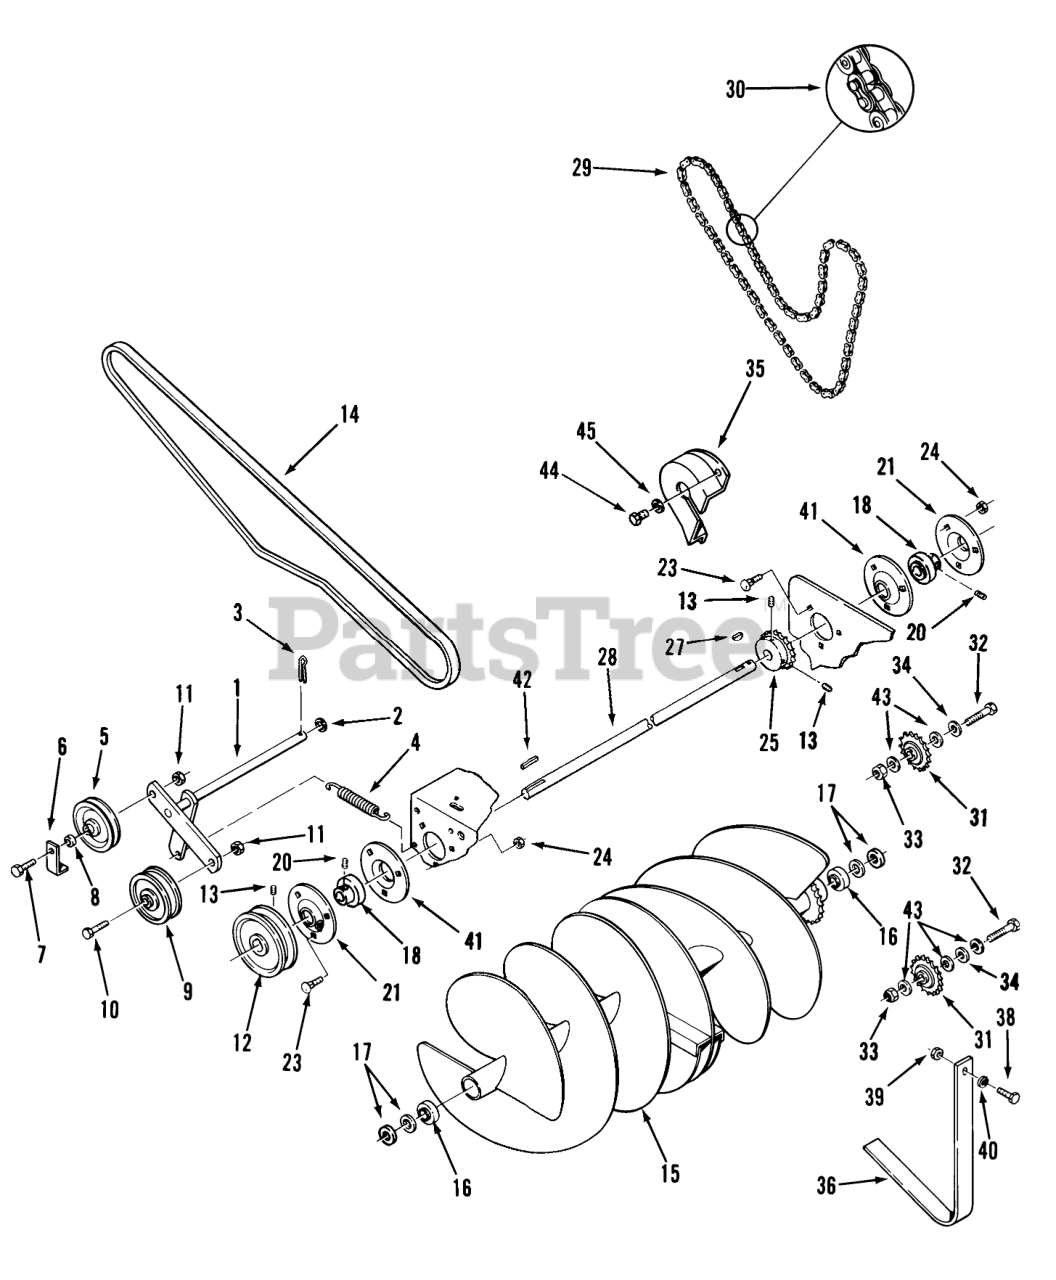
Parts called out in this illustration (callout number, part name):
1	ASSY IDLER ARM R
2	Washer
3	Cotter Pin
4	SPRING R
5	PULLEY-IDLER
6	Spacer
7	Bolt
8	SPACER
9	Idler Pulley
10	BOLT
11	Nut
12	PULLEY
13	Set Screw
14	V-BELT
15	Auger
16	BEARING-BALL
17	Washer
18	BEARING AND COLLAR
20	SET SCREW
21	FLANGE-ZERK RELUBE
23	Bolt
24	Nut
25	Sprocket 14T x 40
27	KEY-WOODRUFF
28	Shaft
29	CHAIN
30	MASTER LINK CHAIN
31	Idler Sprocket
32	Bolt 1/2-13 X 2
33	Eslok Nut
34	SPACER
35	GUARD-CHAIN
36	Guard
38	H H C S
39	Nut 1/4-20
40	WASHER
41	Flange
42	KEY-STRAIGHT
43	Washer
44	Bolt
